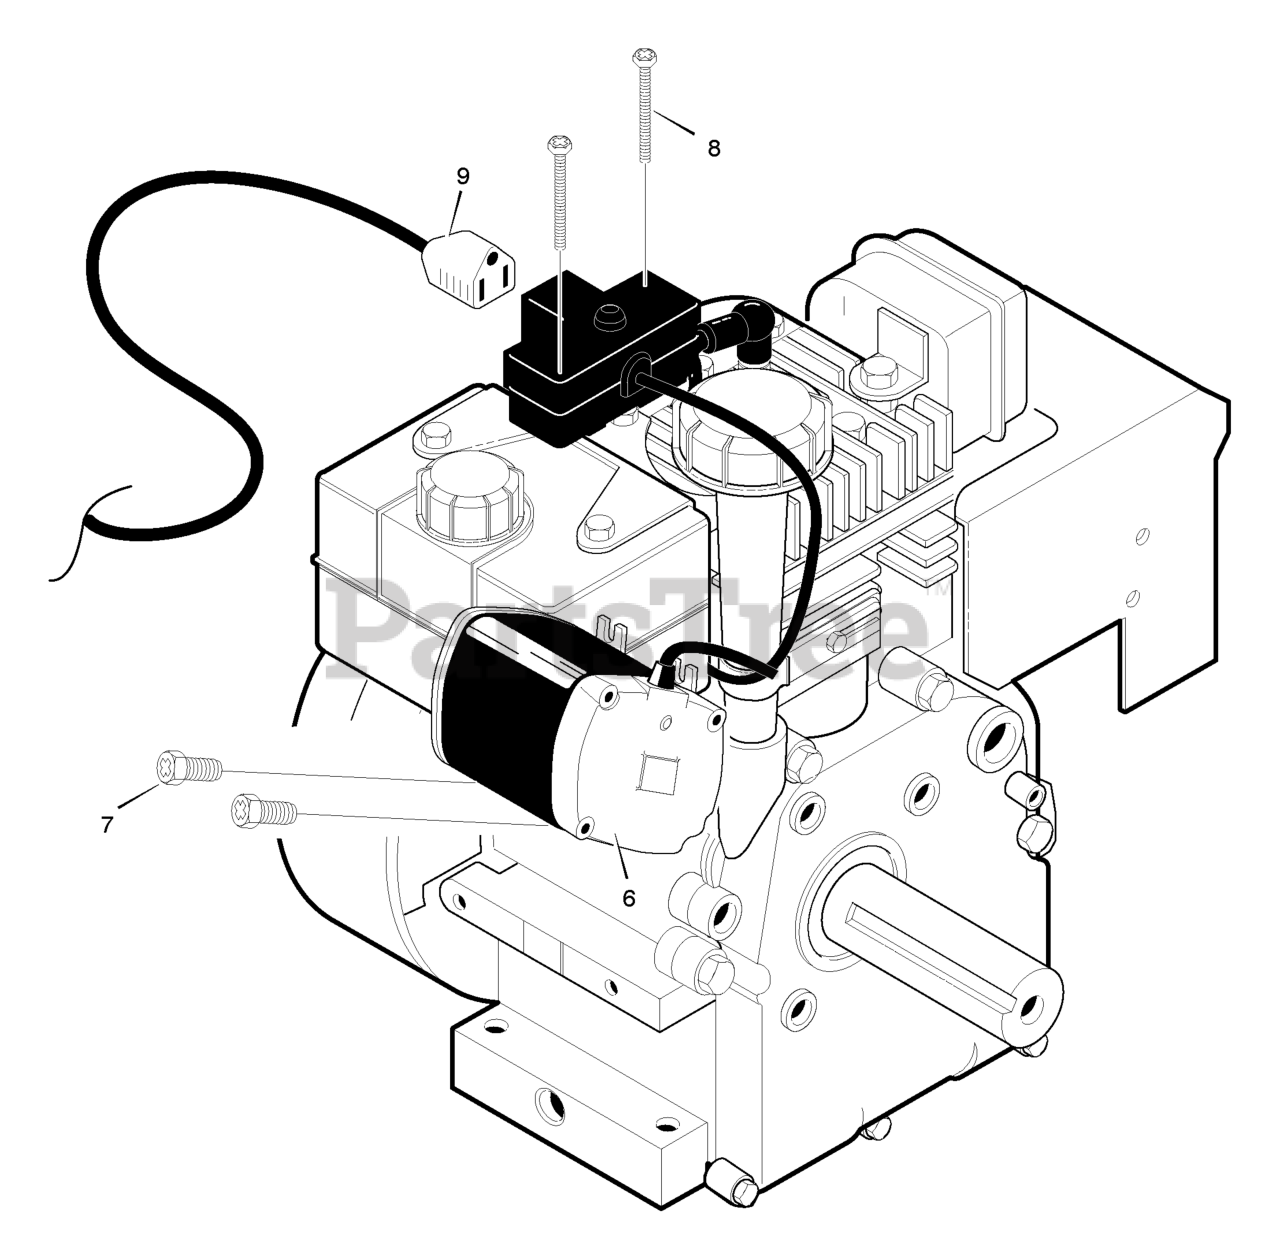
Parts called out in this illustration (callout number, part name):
6	MOTOR, STARTER
8	SCREW
9	CORD, Electric, 10FT. 110V
